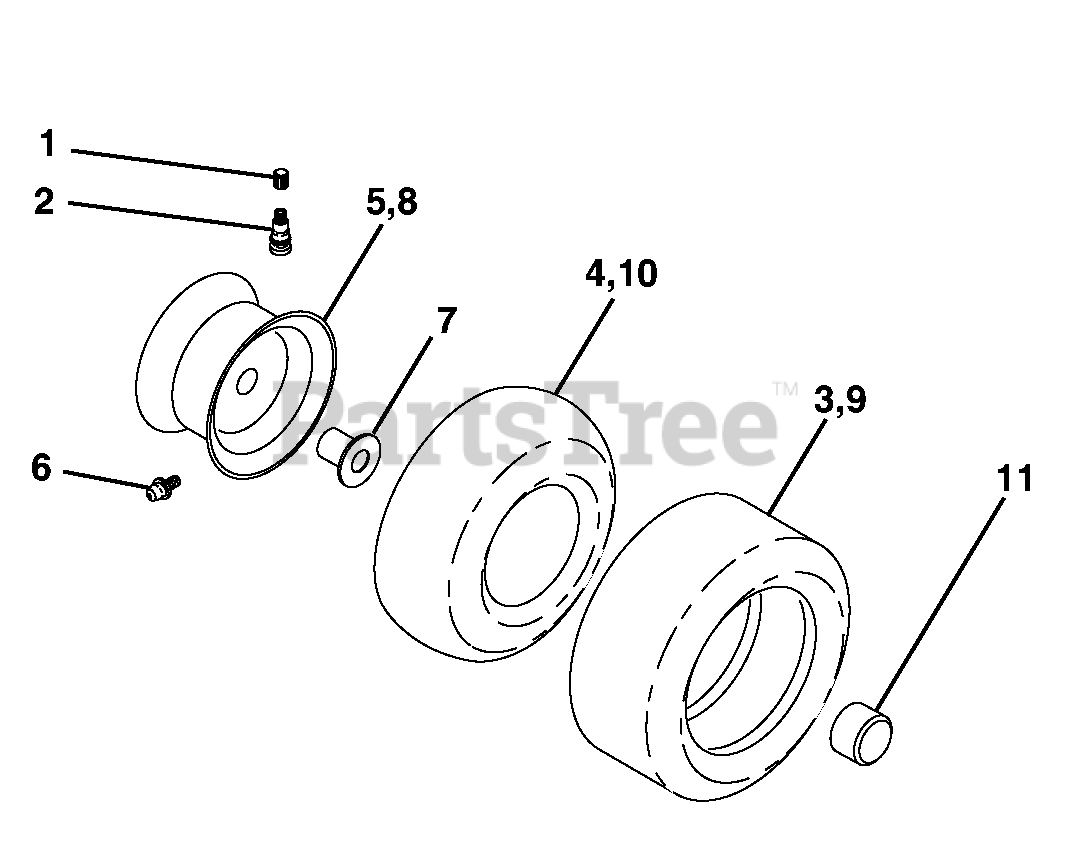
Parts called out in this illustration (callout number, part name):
1	Cap Valve Tire
2	Stem Valve
3	Tire F T 15 x 6 0 - 6 Service
4	Tube Front
5	Rim Asm 6" front Service
6	Fitting Grease
7	Bearing Flange
8	Rim Asm 8" rear Service
9	Tire R T 20 x 8-8 Service
10	Tube Rear
11	Cap Axle Blk 1 50 x 1 00
